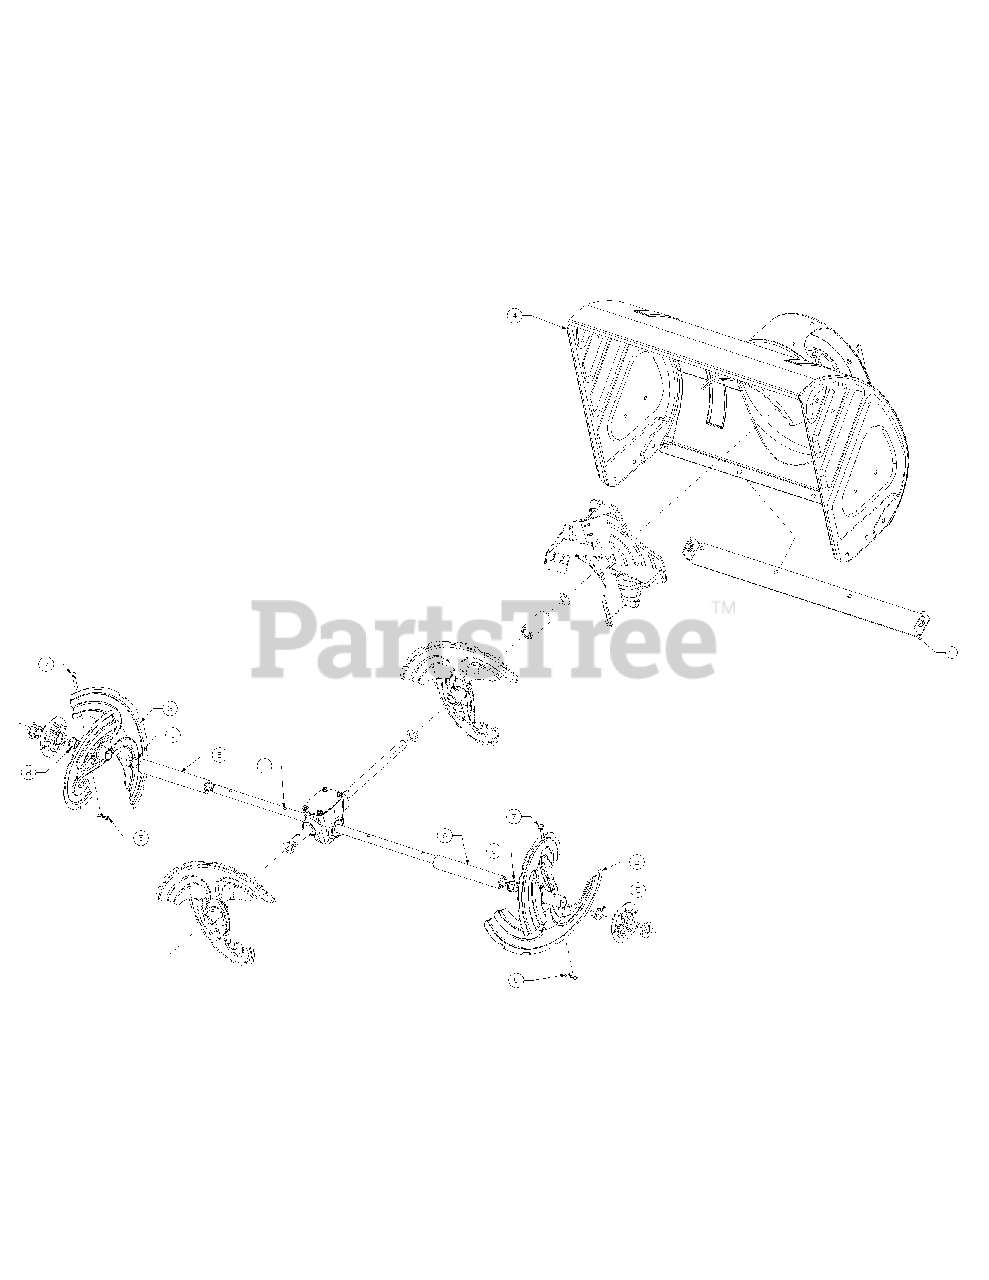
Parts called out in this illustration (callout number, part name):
1	Gearbox Asm-Aug
2	Auger Assembly-LH
3	Auger Assembly-RH
4	Housing-Auger 28"
5	Pin-Cotter
6	Spacer
7	Pin-Shear .25
8	Flange Bearing
9	Plate-Shave 28"
